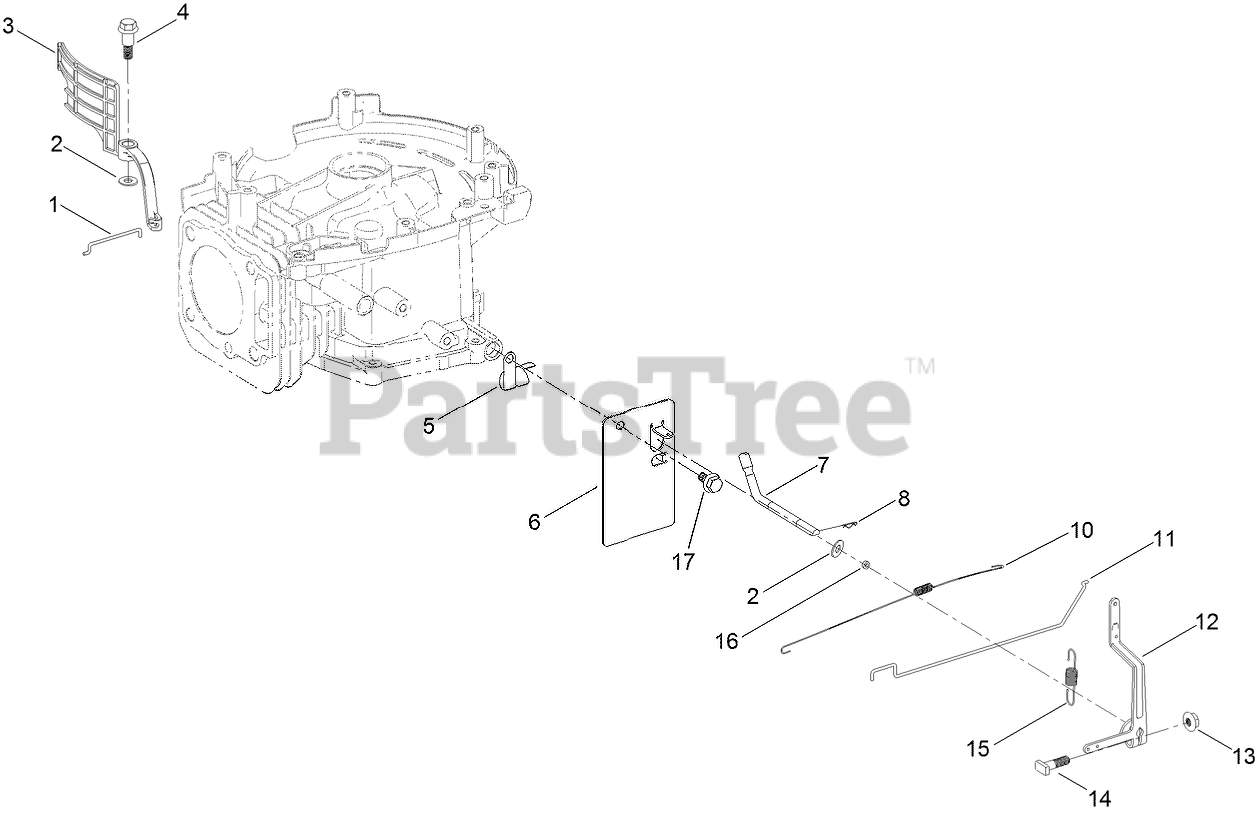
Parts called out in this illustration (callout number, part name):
1	LINKAGE-CHOKE
2	WASHER-FLAT
3	AIR VANE-AUTOCHOKE
4	SCREW-SHOULDER, HWH
5	CLIP-HARNESS, WIRE
6	PLATE-CONTROL, THROTTLE
7	ARM-GOVERNOR
8	PIN-HAIR
10	SPRING-RETURN, THROTTLE
11	ROD-GOVERNOR
12	ARM-GOVERNOR
13	NUT-FLANGE
14	BOLT-ARM, GOVERNOR
15	SPRING-GOVERNOR
16	SEAL-OIL
17	SCREW-HHF
